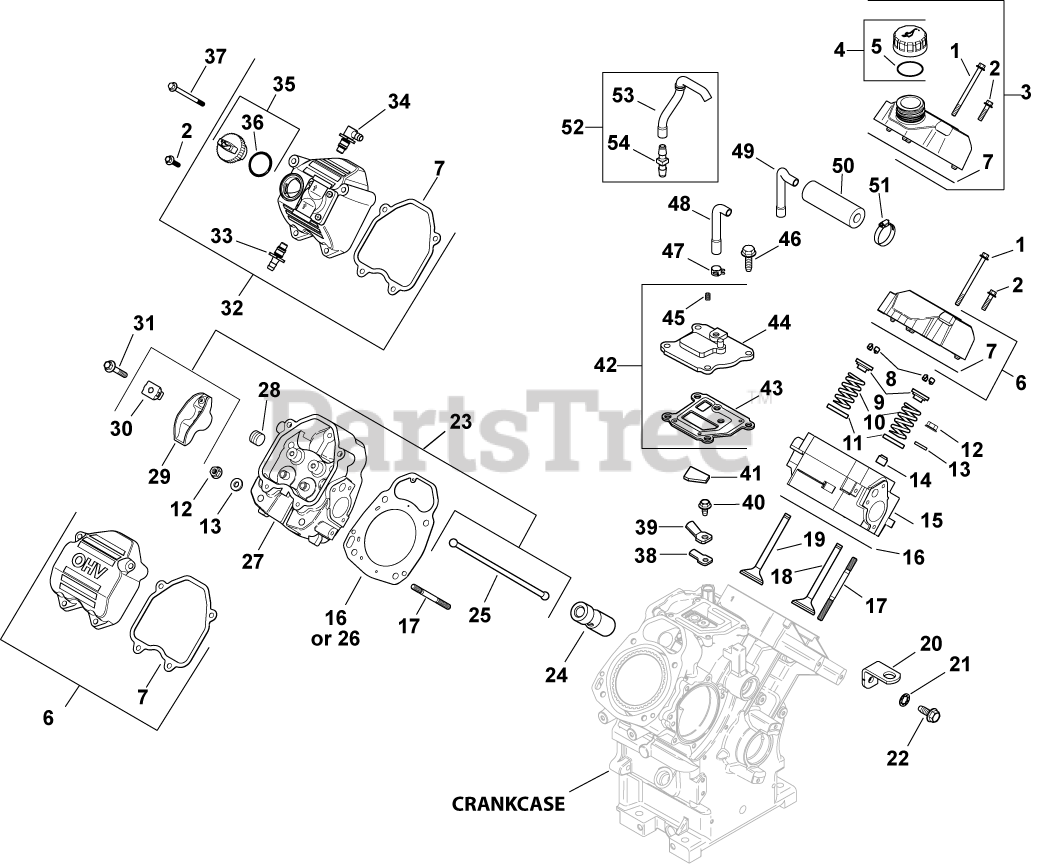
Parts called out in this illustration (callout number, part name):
1	SCREW, FLG M6X1.0X80
6	KIT, ROCKER COVER
7	GASKET, VALVE COVER
8	KIT, RETAINER
9	CAP, VALVE SPRING
10	SPRING, VALVE
11	RETAINER, SPRING
12	NUT, FLG M8X1.25
13	WASHER, FLAT 5/16"
14	SEAL, VALVE STEM - (#2503214S)
15	KIT,CYLINDER HEAD #1
16	GASKET, CYLINDER HEAD-USE 66 841 02-S
18	VALVE, INTAKE (STD)
19	VALVE, EXHAUST (STD) - USE 32 016 01-S
23	KIT, VALVE TRAIN
24	LIFTER, VALVE HYDRAULIC - (#2535111S)
25	ROD, PUSH
27	KIT,CYLINDER HEAD #2
28	PLUG, PIPE
29	ARM, ROCKER
30	PIVOT, ROCKER ARM
32	KIT, FUEL PUMP/ROCKER COVER
33	KIT, STRAIGHT FITTING
34	KIT, 90 DEG. FITTING
35	CAP ASSY, OIL FILL (YELLOW)
37	SCREW, FLG M6X1.0X55
38	REED, BREATHER
39	RETAINER, REED
40	SCREW, FLG THD FRM M5X.8X10
41	FILTER, BREATHER
42	KIT, BREATHER ASSEMBLY
43	GASKET, BREATHER
44	KIT, BREATHER COVER USE 24 033 01-S
45	PLUG, CTSK PIPE 1/8"
47	CLAMP, BAND SPRING HOSE-(#2523737S)
48	HOSE, BREATHER
51	CLAMP, HOSE (KM)-USE 25 237 31-S
